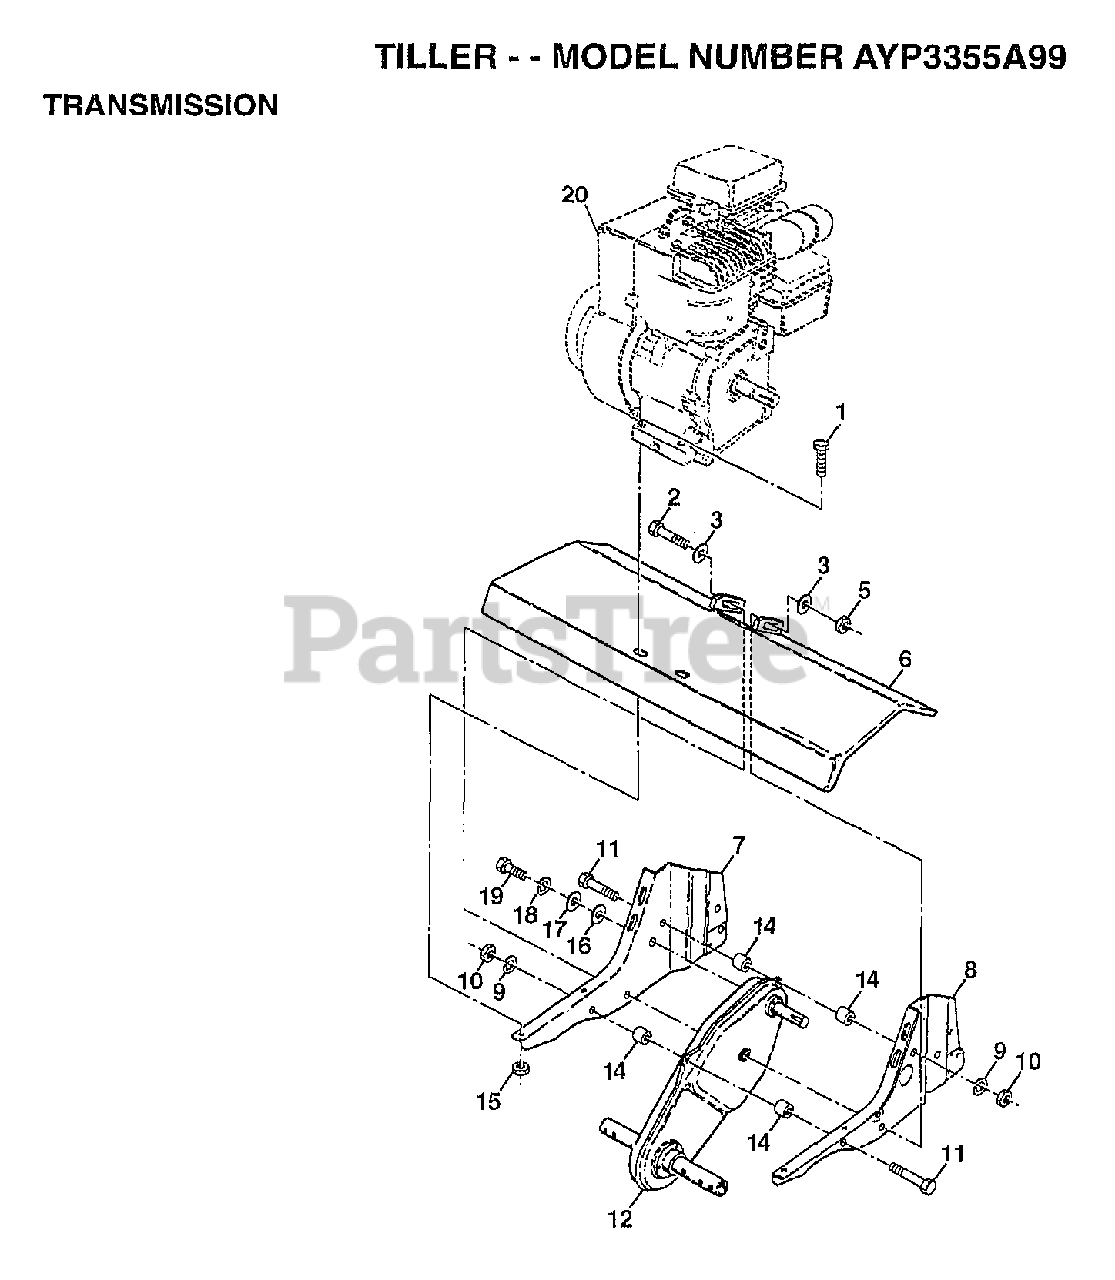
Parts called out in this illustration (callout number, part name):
1	BOLT.HEX.5/16-1.5
2	BOLT HEX 3/8-16
3	WASHER
5	NUT
6	TINE SHIELD
7	BRACKET.ENGINE.RH
8	ENGINE BRKT LH TI
9	LOCKWASHER
10	NUT.HEX.5/16-18
14	SPLIT SPACER RT
16	WASHER
17	WASHER
18	LOCKWASHER
19	BOLT
